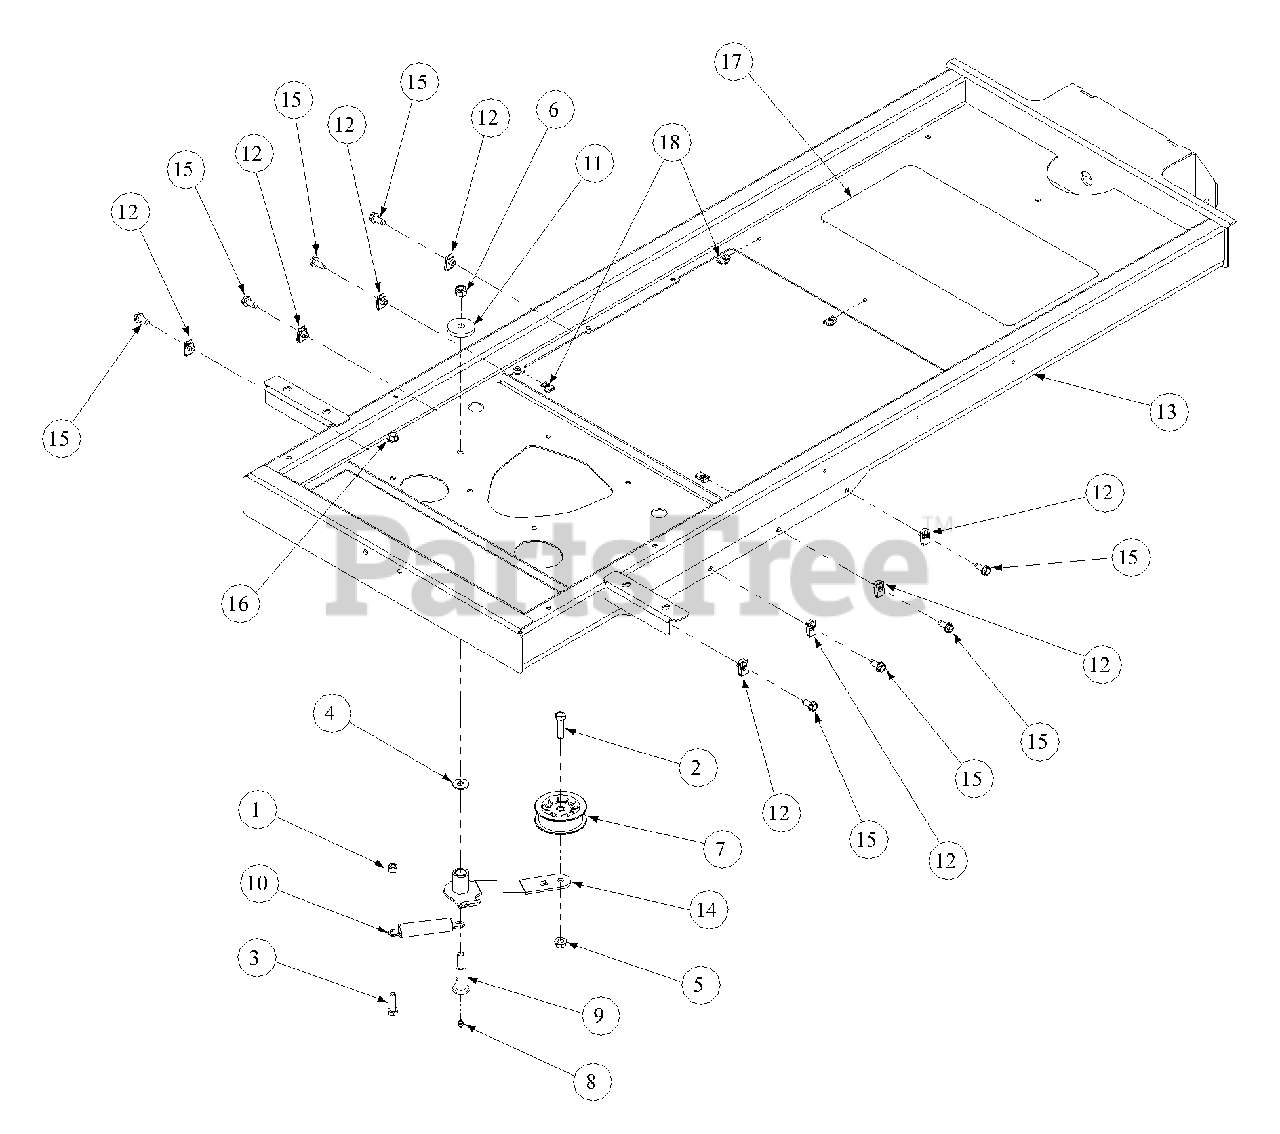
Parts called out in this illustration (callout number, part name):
1	Hex Nut, 5/16-18
2	Hex Cap Screw, 3/8-16 x 1-1/2
3	Hex Cap Screw, 5/16-18 x 1-1/4
4	Flat Washer, 3/8 zinc
5	Hex Nut, 3/8-16 Flange Lock
6	Nylock Nut, 7/16-14
7	Flat Idler Pully w/ adaptor
8	Grease Fitting, 1/4-28 x 3/16
9	Shoulder Bolt
10	Extension Spring, .865 OD x 4.68 lg
11	Flat Washer, 7/16 ID x 1.75 OD
12	U-Nut, 5/16-18
13	Frame Assembly Weldment
14	Idler Arm Assembly
15	Hex Washer Screw 5/16-18 x .750
16	Nut, 5/16-18, Hexflange Lock
17	Abrasive Foot Pad
18	U-Nut, 1/4-20
